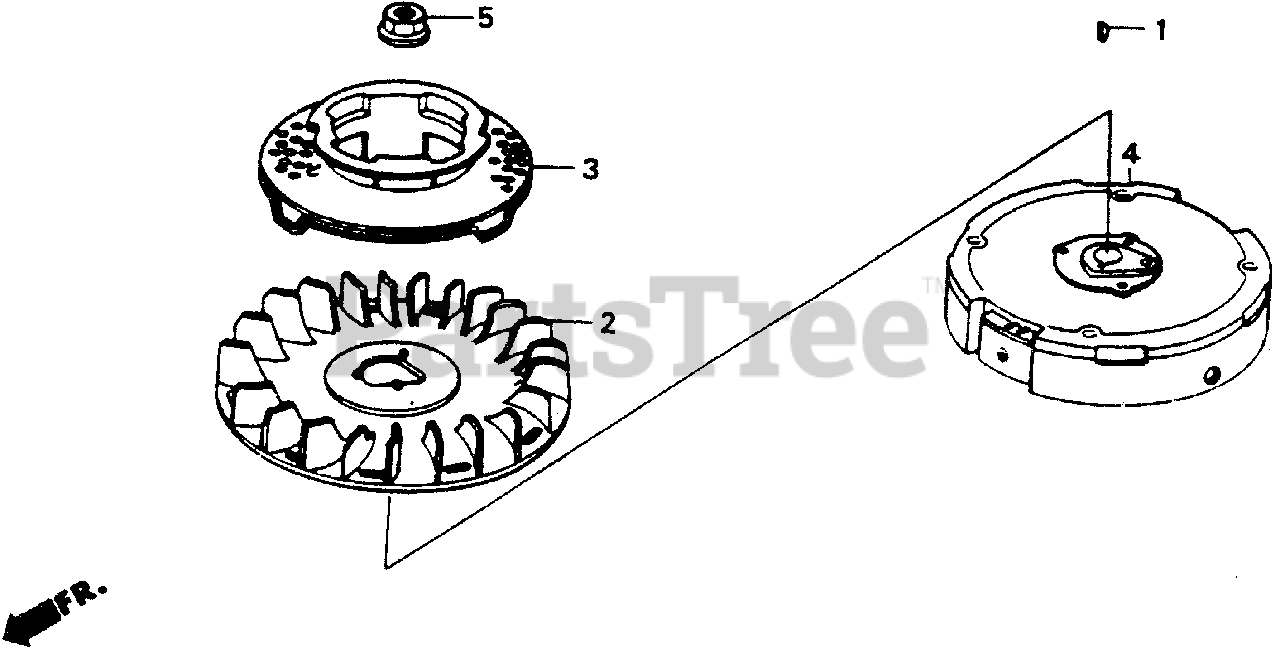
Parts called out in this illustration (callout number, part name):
1	KEY, SPECIAL WOODRUFF (25X18)
2	FAN, COOLING
3	PULLEY, STARTER
4	FLYWHEEL (STD)
5	NUT, SPECIAL (14MM)
